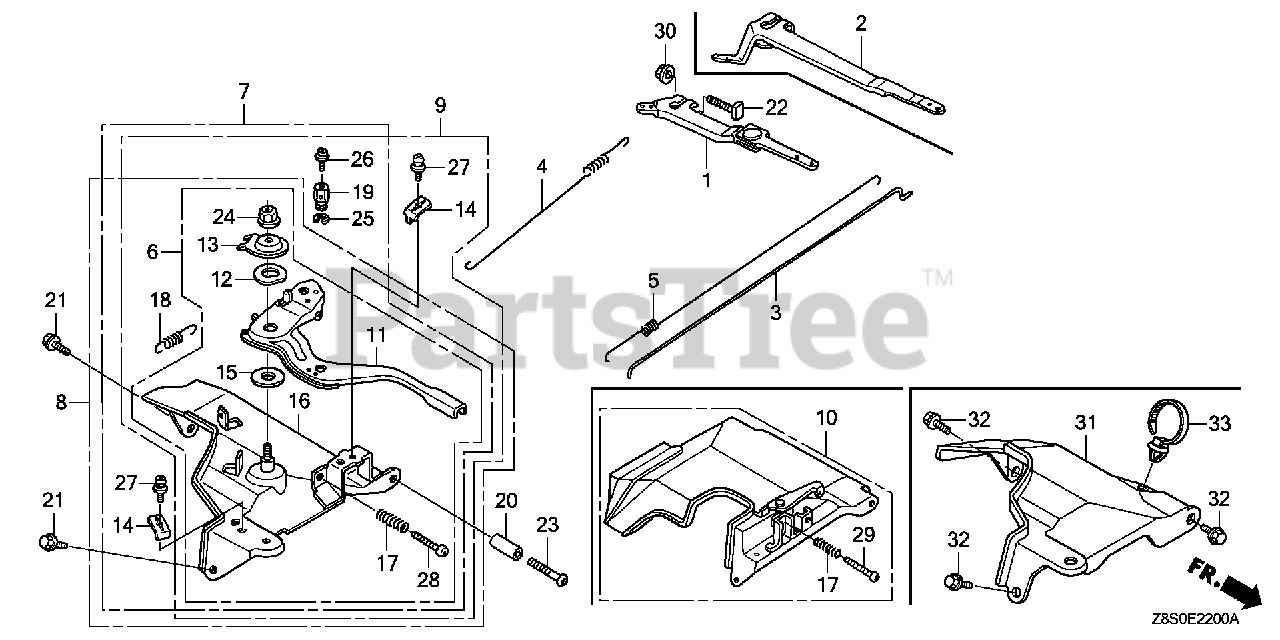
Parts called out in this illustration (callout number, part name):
2	ARM, GOVERNOR
3	ROD, GOVERNOR
4	SPRING, GOVERNOR (L=145.0MM) (WIRE DIAMETER 1.0MM)
5	SPRING, THROTTLE RETURN
8	CONTROL ASSY. (REMOTE)
11	LEVER, CONTROL
12	SPRING, LEVER
13	WASHER, CONTROL LEVER
14	HOLDER, CABLE
15	SPACER, CONTROL LEVER
16	BASE, CONTROL
17	SPRING, CONTROL ADJUSTING
18	SPRING, CABLE RETURN
21	BOLT, FLANGE (6X12) (CT200)
22	BOLT, GOVERNOR ARM
24	NUT, SELF-LOCK (6MM)
27	SCREW, PAN (5X16)
28	SCREW, PAN (5X28)
30	NUT, FLANGE (6MM)
